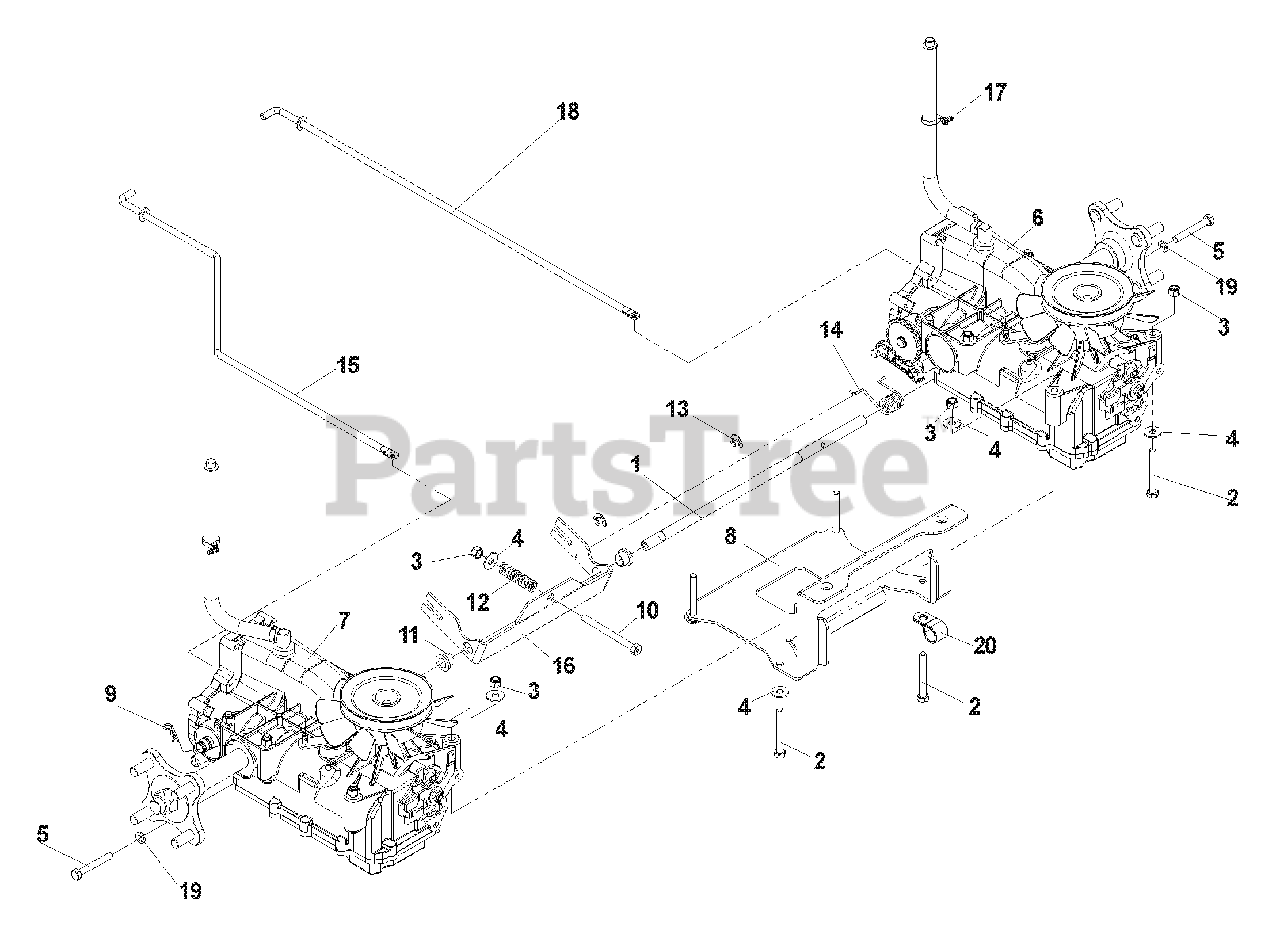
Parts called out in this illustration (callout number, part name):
2	HCS 5/16C X 2 1/2
3	NUT, 5/16C, NYLOC
4	WASHER, 5/16, FLAT
5	HCS 5/16C X 2 1/4, GR. 8
8	IZT SUPPORT
9	HAIRPIN COTTER
10	BOLT, BRAKE
11	BUSHING, NYLON FLANGED
13	E-RING, 1/2"
14	SPRING-TORSION
15	BYPASS LINKAGE, RIGHT
16	BRAKE "U" ARM
18	BYPASS LINKAGE, LEFT
19	LOCKWASHER 5/16
